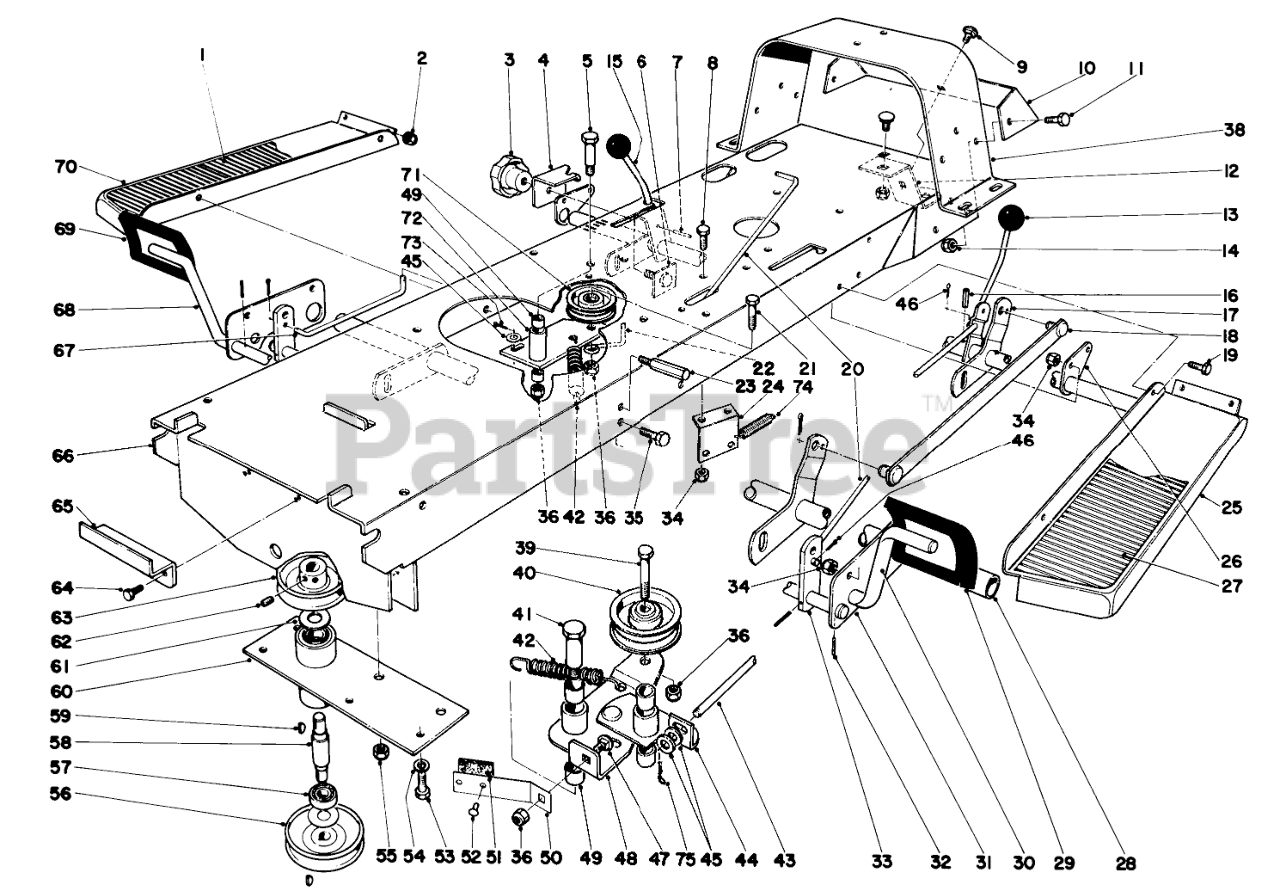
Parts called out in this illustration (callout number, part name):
1	Foot Pad
2	NUT-KEPS
4	Slide Height Adj.
5	Shoulder Bolt
6	Knob Plate
7	PIN-ROLL
8	SCREW-HH
9	SCREW-CARR
10	Frame Member Rear
11	SCREW-HH
12	Bracket Hitch
13	Knob
15	Rod Control Hgt. Adj.
16	PIN-ROLL
17	Rear Height Adj. Tube
18	Height Adj. Link
19	SCREW-HH
20	Brake Rod
21	SCREW-HH
22	Belt Retainer
23	Pedal Stop
24	Belt Guide
25	Footrest
26	Bracket Tube
27	Foot Pad L.H.
28	Front Height Adj. Tube
29	CLUTCH PAD
30	Clutch Pedal
31	Plate Tube
32	PIN-SPRING
33	Arm Lever
34	Nut
35	SCREW-HH
38	Rear Support
39	SCREW-HH
40	Pulley
41	Shoulder Bolt
42	Spring Tension
43	Clutch Rod Blade
44	Pivot Bracket
45	WASHER-FLAT
46	PIN-COTTER
47	SCREW-CARR
48	Idler Plate
49	Bushing
50	Clutch Brake
51	BLADE BRAKE LINING
52	Rivet
53	SCREW-HH
54	WASHER-LOCK
56	Pulley
57	Bearing
58	Pulley Shaft
59	KEY-WOODRUFF
60	Pulley Tube
61	Bearing Washer
62	SCREW-SET, HSH
63	Pulley
64	SCREW-HH
65	Spring Clip
66	Frame
67	Clutch Rod
68	Brake Pedal
69	PAD-BRAKE
70	Footrest
71	Pulley
72	Idler Arm
73	PIN-COTTER
74	Spring
75	Hair Pin Cotter
